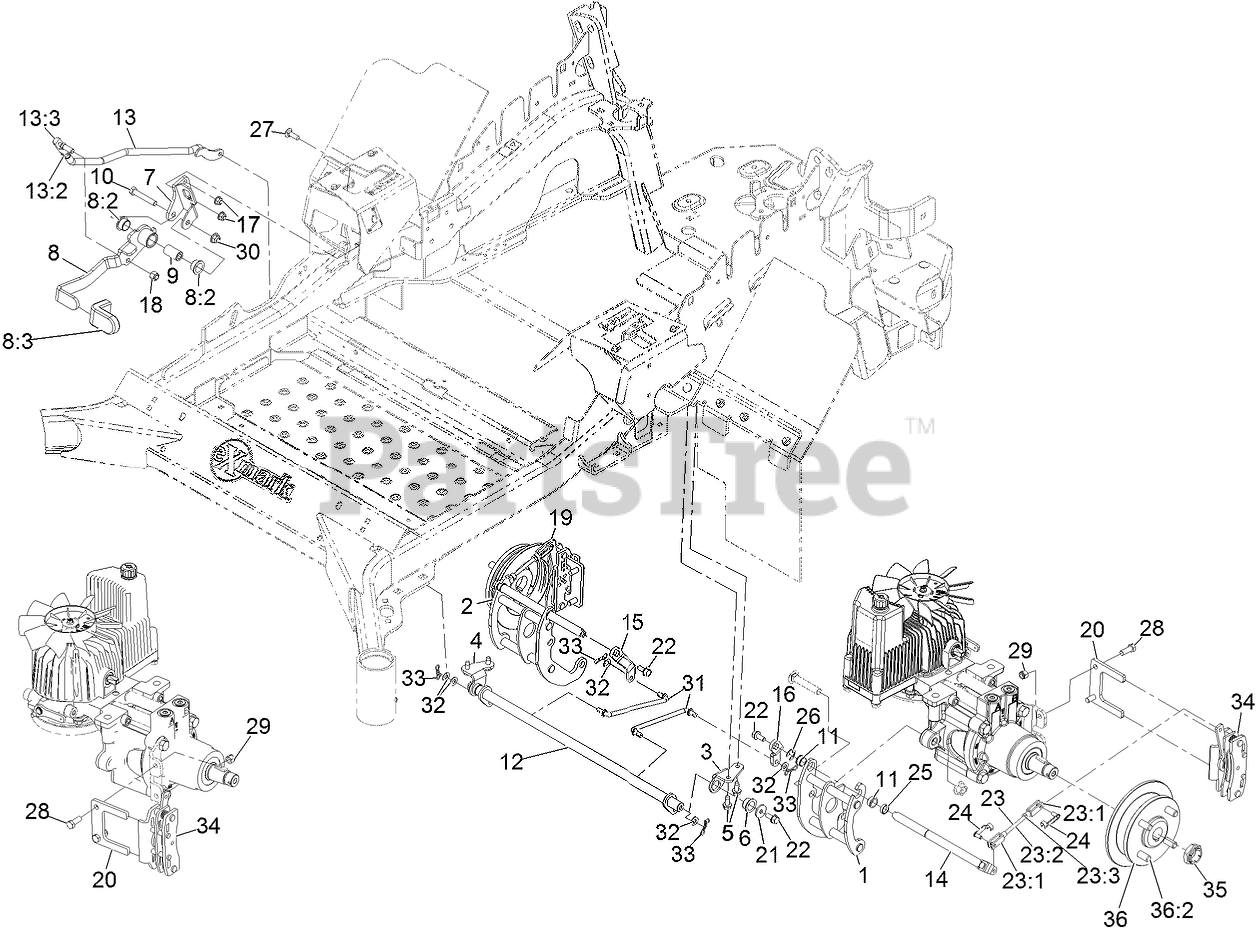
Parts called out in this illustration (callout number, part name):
1	MOUNT-BELLCRANK, LH
2	MOUNT-BELLCRANK, RH
3	MOUNT-PIVOT, LH
4	MOUNT-PIVOT, RH
5	Screw-HWH 5/16-18 X 3/4 Tf
6	BUSHING-FLANGE
7	BRACKET-MOUNT
8	Brake Lever ASM
8:2	BUSHING-FLANGE
8:3	GRIP-LEVER
9	HANDLE-PIVOT, BRAKE
10	SCREW-HH
11	BUSHING
12	Shaft-Cross
13	Front Linkage ASM
13:2	END-TIE ROD, RH
13:3	NUT-HJ
14	Bellcrank
15	ARM-INNER, RH
16	ARM-INNER, LH
17	NUT-HF, NI
18	NUT-LOCK
19	Caliper-Brake, RH
20	PLATE-MOUNT, BRAKE
21	WASHER-FLAT
22	SCREW-HHF
23	REAR LINKAGE ASM
23:3	NUT-JAM
24	PIN-CLEVIS, SPRING
27	BOLT-CARR
28	SCREW-HH,
29	NUT-LOCK
30	NUT-HF, NI
31	Link-Mid
32	WASHER-PLAIN
33	PIN-COTTER, LOCKING
34	Caliper-Brake, LH
35	LOCKNUT
36	Wheel Hub ASM
36:2	STUD-WHEEL
